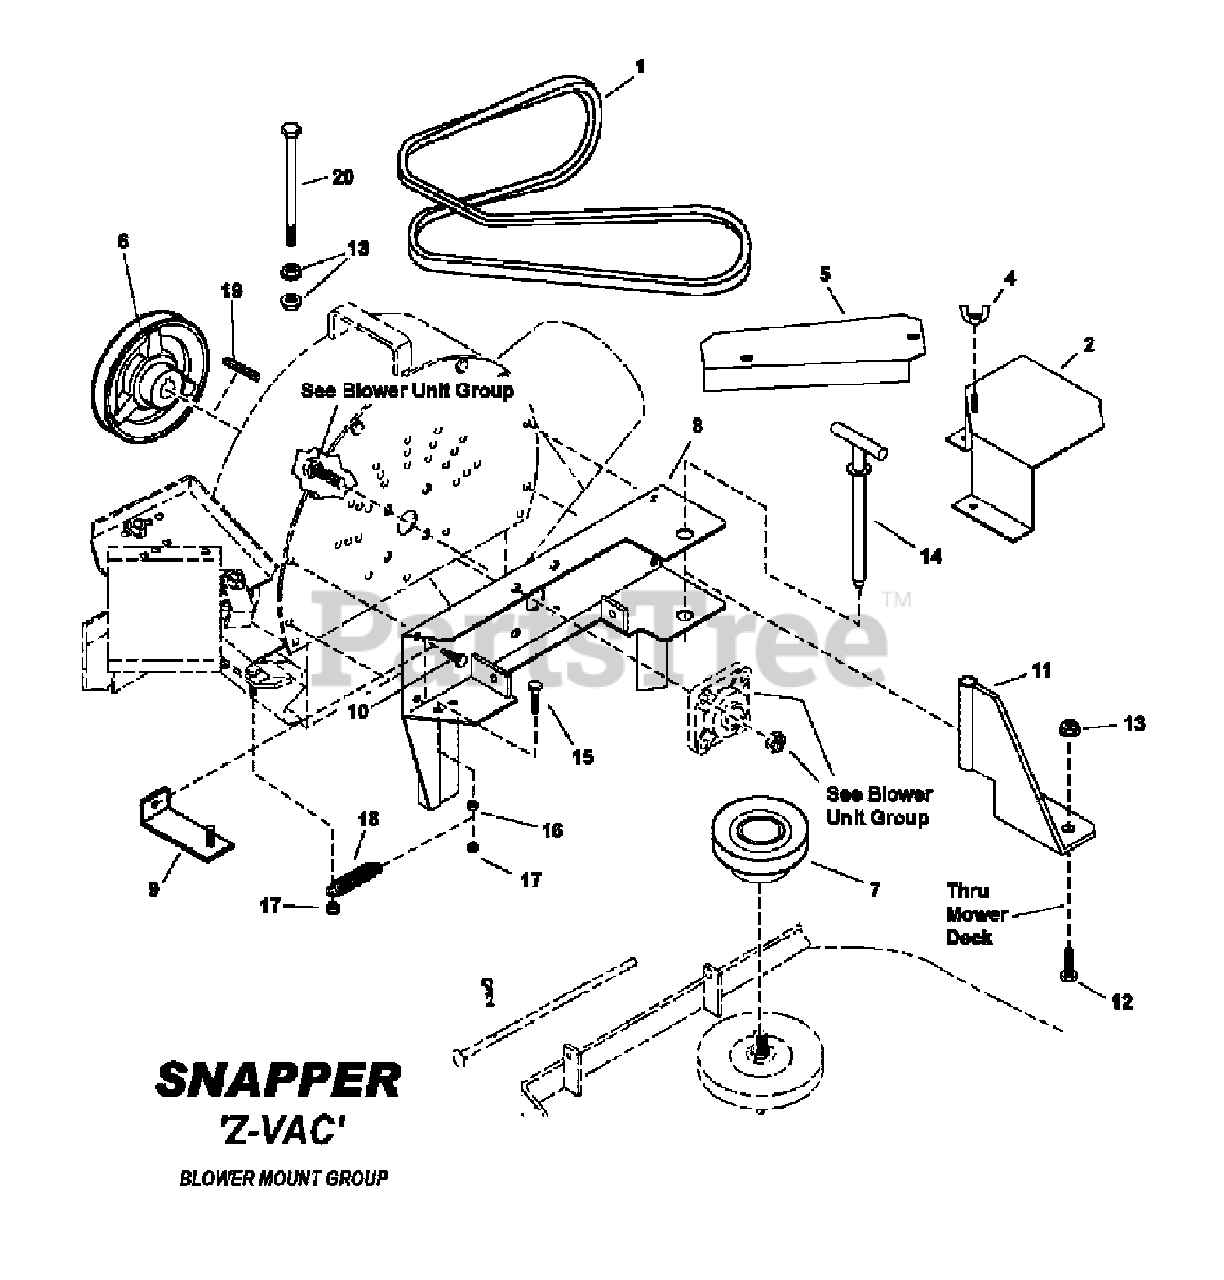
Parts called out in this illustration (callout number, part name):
1	BELT, A-92.0
2	GUARD, Pulley
4	LOCKNUT, Wing 5/16 - 18 - YZ
5	BELT GUARD, Deck Belt (61")
6	PULLEY, Blower Input (61")
7	PULLEY, Spindle
8	WELDMENT, Blower Mount (61")
9	BRACKET, Guard Support
10	SCREW, Hex Washer Self-Tap 5/16-18 X 3/4-YZ
11	BRKT, Deck Mount Weldment
12	SCREW, Hex Head Cap 3/8-16 X 1 YZ
13	NUT, Flange Lock, 3/8-16 YZ
14	PIN, T-Handle
15	SCREW, Hex Head Cap 5/16-18 X 1.25 GR 5 YZ
16	NUT, Flange Lock,, 5/16-18 YZ
17	NUT, Hex Cap Lock Large, 5/16C BZ
18	SPRING, Idler
19	KEY, 1/4X1/4X1.44
20	SCREW, Hex Head Cap 3/8-16 X 6 YZ
